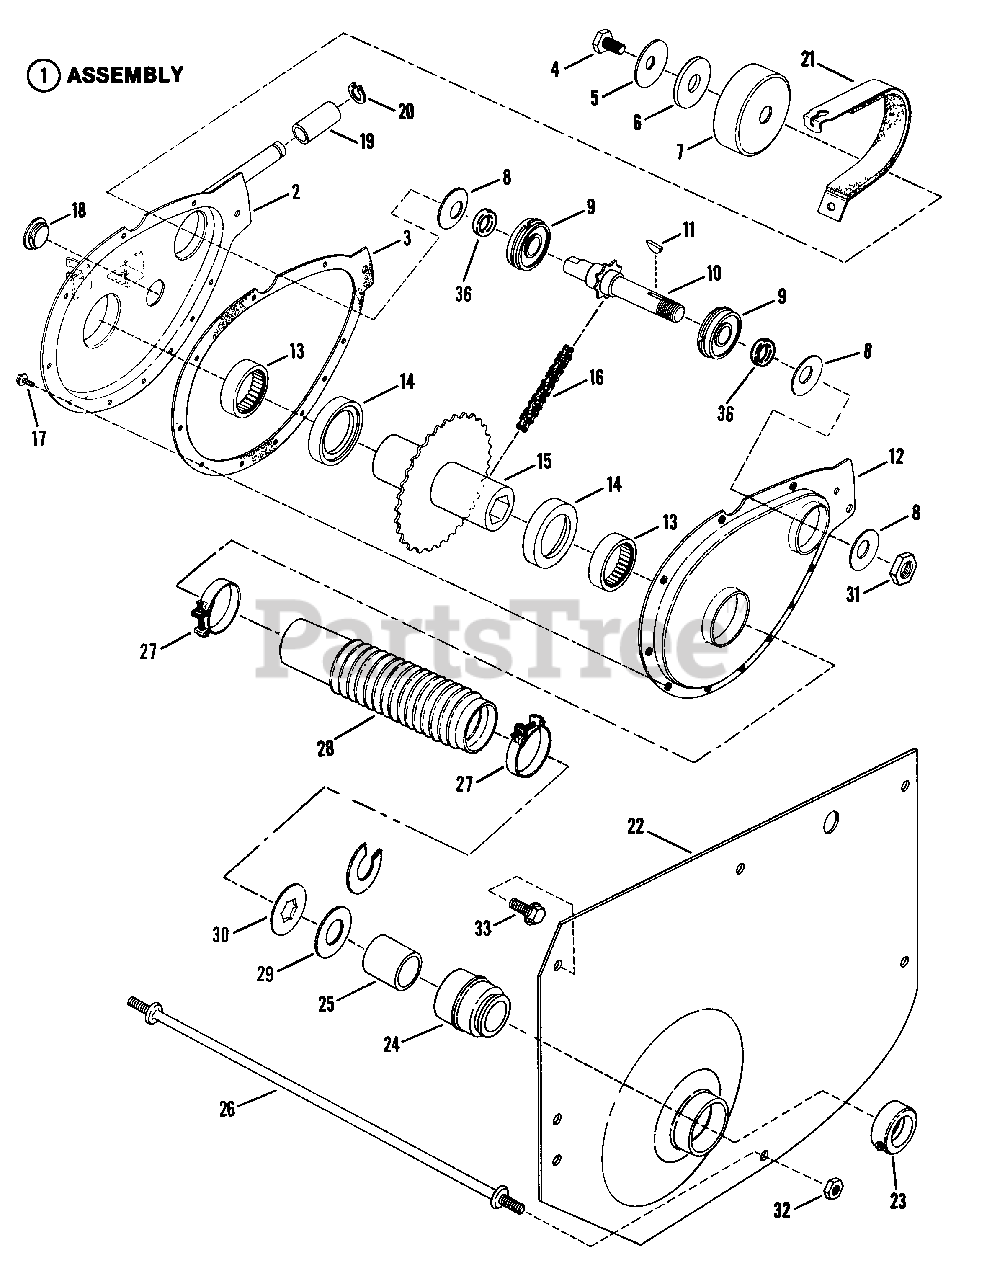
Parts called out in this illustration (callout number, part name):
1	ASSEMBLY, Chain Case
2	CASE, Sprocket
3	GASKET, Case-Cover
4	SCREW, 3/8-24x1/2" Hex Head Cap
5	WASHER
6	WASHER, Brake Drum
7	DRUM, Auxiliary Brake
8	WASHER, Belleville
9	BEARING, Ball
10	SPROCKET & SHAFT
11	KEY, Woodruff
12	COVER, Chain Case
13	BEARING, Needle
14	WASHER, Nylon Thrust
15	HUB & SPROCKET
16	CHAIN
17	SCREW, #10-24 x 1/2" Hex Washer Self-Tap (Torx)
18	PLUG, Oil Fill & Check
19	ROLLER
19A	ROLLER
20	RING, Retaining
21	BAND, Auxiliary Brake
22	FENDER, Left Hand
23	COLLAR, Lock
24	BEARING, Left Hand Fender
25	SPACER, Left Hand
26	ROD, Cross-Tie
27	CLAMP, Boot
28	BOOT, Oil Seal
29	WASHER, Thrust Nylon
30	WASHER, Thrust
31	LOCKNUT, 5/8-18 Hex
32	NUT, 5/16-24 Hex
33	SCREW, 5/16-18 x 5/8" HW Self-Tapping
36	"O" Ring
